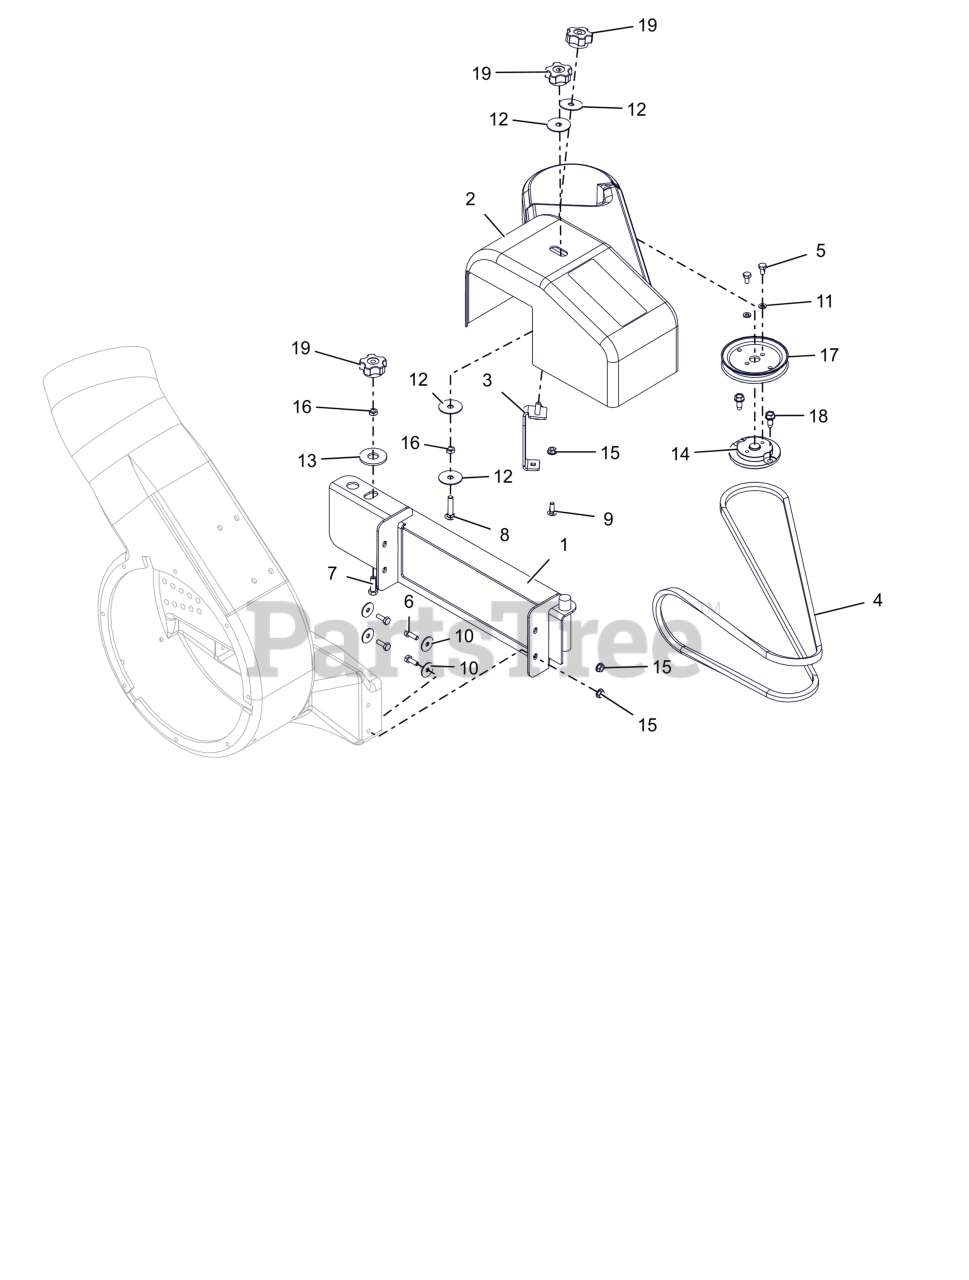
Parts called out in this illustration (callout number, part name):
1	WLDMT, PUMP MOUNTING (BLACK)
2	COVER, BAGGER BELT -W/DECAL
3	WLDMT, BAGGER BELT COVER BRKT
4	V-BELT, 4L-RAW EDGE
5	BLT,HEX .25-20X.50 G5 ZCC
6	BLT, HEX .25-20X.75 G5 ZCC
7	BLT, HEX .31-18X1.00 G8 ZCC
8	BLT,RHSN .31-18X1.50 G5 ZCC
9	BLT, RHSN .25-20X.750 G5 ZCC
10	WSHR,FLT .281X1.000X.063 ZCC
11	WSHR,LK-REG .250X.062 ZCC
12	WSHR,FLT .380X1.50X.062 ZCC
13	WSHR,FLT .688X1.75X.134 ZCC
14	ADAPTOR, BAGGER SHEAVE
15	NUT-LK-TOP-FLG .250-20 GF ZCC
16	NUT-JAM .312-18 G2 ZCC
17	SHEAVE, SPINDLE (4.25 HA )
18	SCR,TAP .312-18X.75 HWH TR ZCC
19	KNOB-CLAMPING, .312-18 NYLOC
